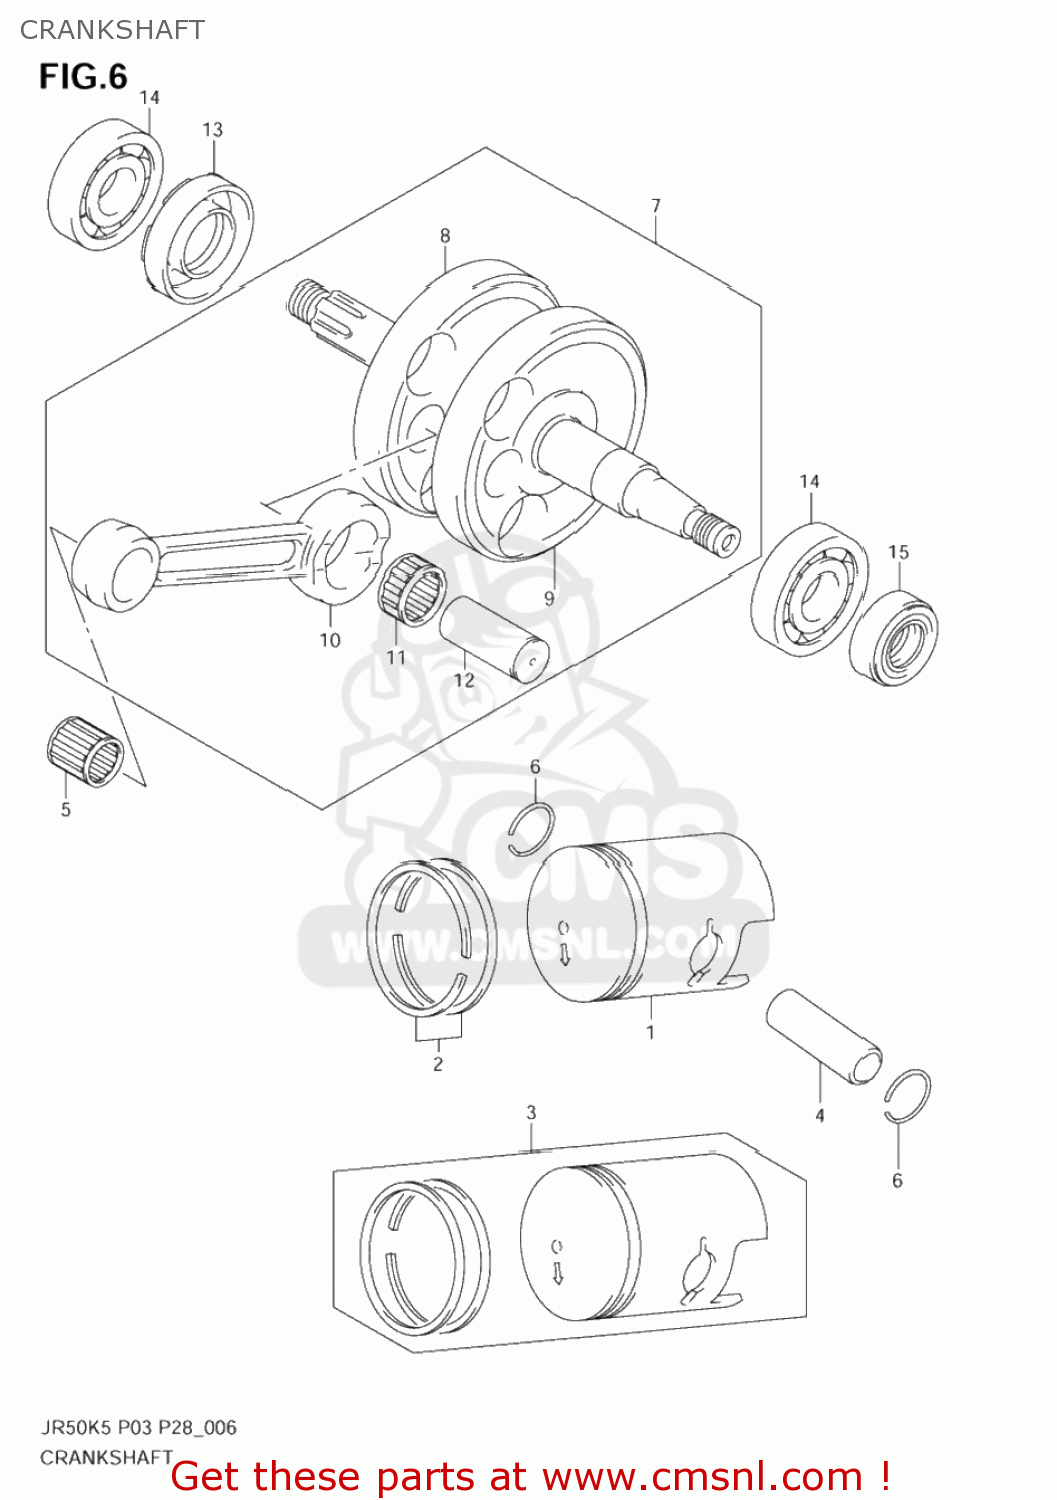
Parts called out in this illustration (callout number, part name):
1	PISTON
2	RING SET,PISTON
3	PISTON SET(OS:0.5)
4	PIN,PISTON
5	BEARING(12X16X16)
6	RING,SNAP
7	CRANKSHAFT ASSY
8	CRANKSHAFT,R
9	CRANKSHAFT,L
10	ROD,CONNECTING
11	BEARING(15X21X9.8)
12	PIN,CRANK
13	SEAL,OIL(22X40X8)
14	BEARING(17X40X12)
15	OIL SEAL (17X29X7)
